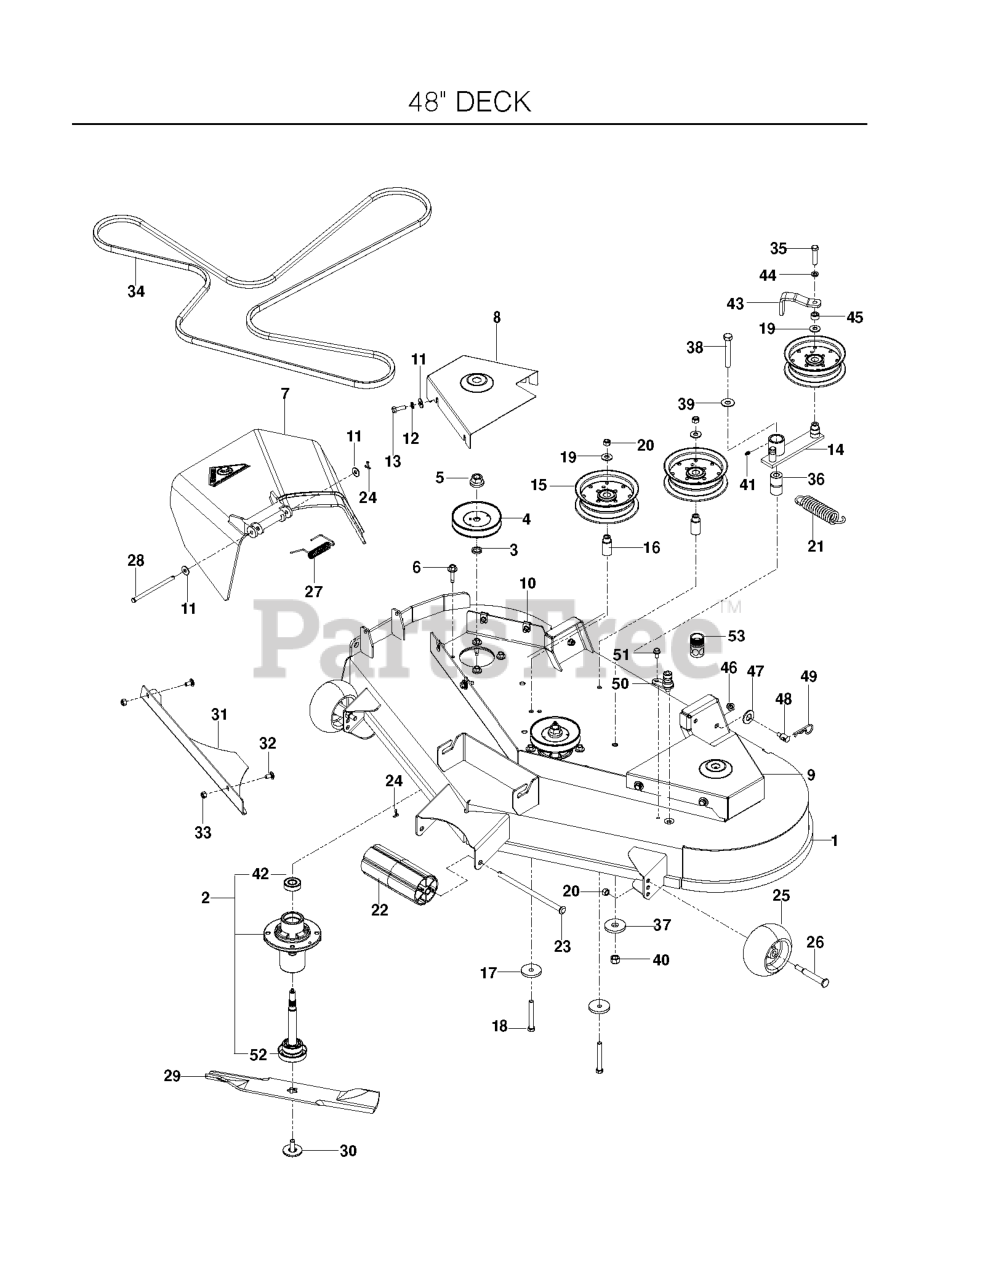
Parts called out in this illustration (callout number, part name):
1	DECK.48".TRI-FORCE.W/DECALS.OR
2	MANDREL.DECK.ASSEMBLY
3	WASHER-SPACER
4	MANDREL PULLEY
5	LOCKNUT - 9/16
6	WASHER HEAD SCREW
7	DISCHARGE CHUTE 48"
8	BELT SHIELD - R.H. ORANGE
9	BELT SHIELD - L.H. ORANGE
10	U-CLIP 5/16-18 NUT RETAINER
11	WASHER 5/16 FLAT
12	WASHER.LOCK.HVY.HLCL.SPR.5/16
13	HCS 5/16C X 1
15	PULLEY, IDLER
16	IDLER BUSHING
17	SPINDLE WASHER
18	HCS 3/8C X 3
19	WASHER 3/8 FLAT
20	NUT 3/8-16 NYLOC
22	NOSE ROLLER 48"
23	ROD.ROLLER.NOSE.NARROW.48"
24	RP_COTTER PIN 1/8 X 3/4
25	GAUGE WHEEL
26	SHOULDER BOLT 1/2X2-5/8 ZD SPE
27	SPRING - TORSION
28	PIN-CLEVIS 5/16 DIA X 5.19 ZD
29	BLADE, 16-1/4"
30	BLADE BOLT ASSY-7/16" TB REPL
31	CONFINEMENT PLATE 48" BLK
32	CARRIAGE BOLT 5/16C X 5/8"
33	NUT 5/16 NYLOC
34	BELT, DECK
35	HCS 3/8-16 X 1 3/4 GR5
36	PIVOT BUSHING
37	WASHER, SUPPORT
38	HCS 1/2C X 3 1/4
39	WASHER 1/2 FLAT
40	NUT 1/2-13 HEX NYLOC ZD
41	ZERK
42	BEARING, BALL
43	GUIDE, BELT
44	FLAT WASHER 5/16 SAE
46	5/16-18 NYLOC FLANGE NUT
47	WASHER 5/8 FLAT
48	STUD.FASTNER.W/ANTI-ROTATE
49	HAIRPIN #4
50	PORT.WASHOUT
51	BOLT 1/4-20 X 1/2 HWST
52	GREASABLE MANDREL SHAFT
53	COUPLING.QUICK CONNECT
